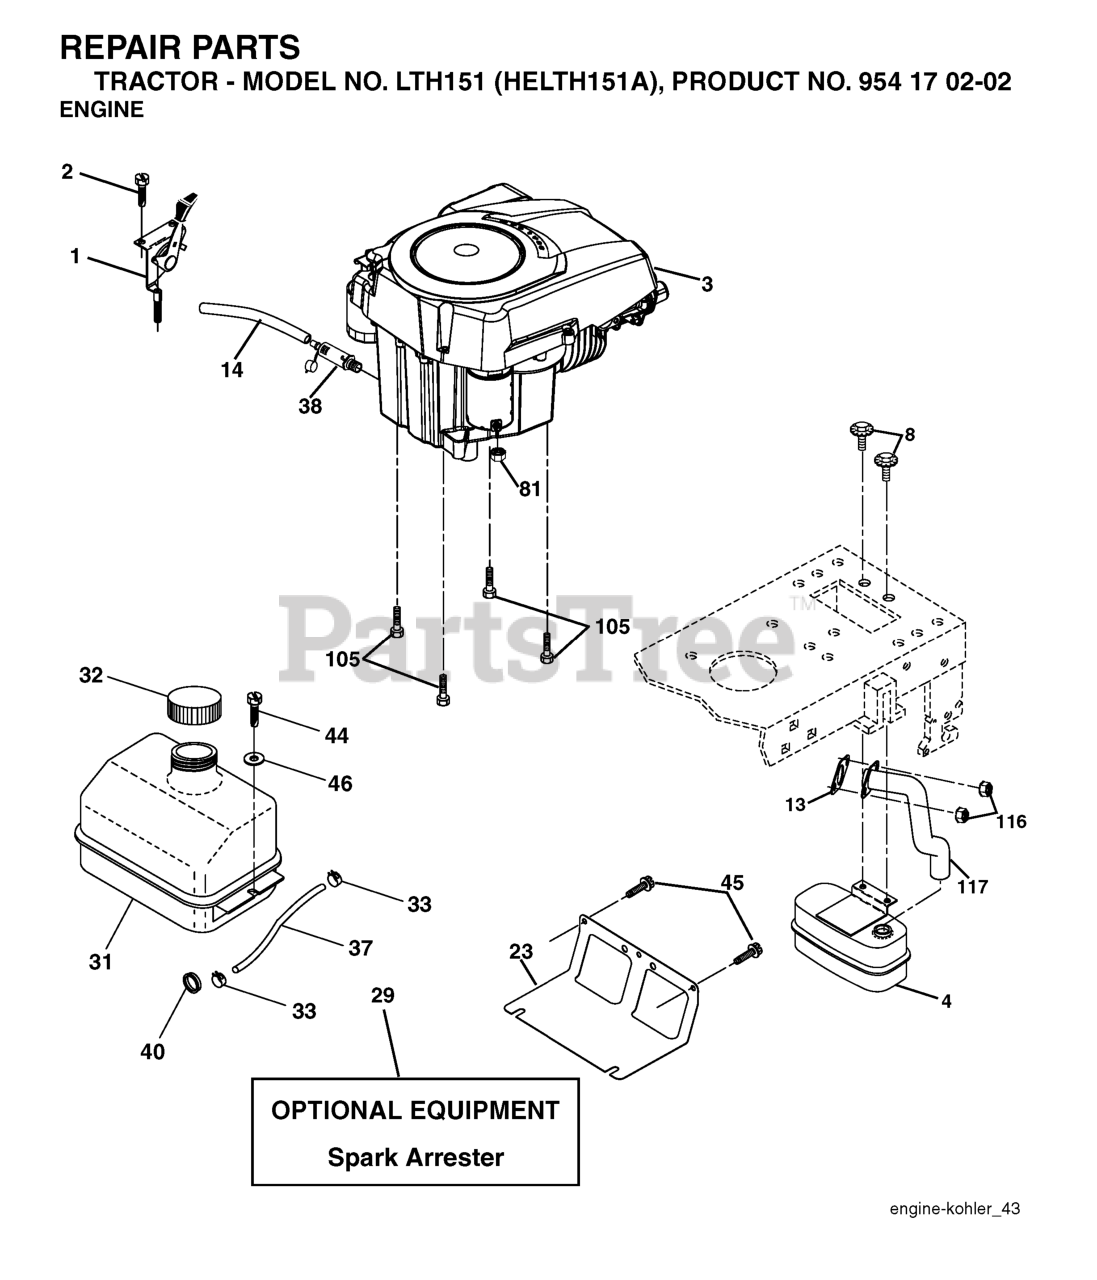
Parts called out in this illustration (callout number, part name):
1	CONTROL.THROTTLE.LT/YT
2	SCREW
4	MUFFLER.SINGLE.CYL.KOHL/B&S
8	BOLT.5/16-18UNCX3/4 W/SEMS.BLK
13	GASKET.EXHAUST.KOHLER
14	TUBE, DRAIN OIL ASM.
23	SHIELD.BROWNING.DBR.GUARD
29	KIT.SPARK ARRESTOR 794945 B&S
31	TANK.ASM.FUEL.FRONT.W/CAP
32	FUEL CAP
33	HOSE CLAMP
37	LINE.FUEL.20
38	PLUG DRAIN OIL EASY
40	BUSHING.SNAP.NYL.BLK.
44	SCREW HEXWSHR 1/4-20X3/4
45	SCREW, 3/8-16X3/4
46	WASHER
81	NUT
105	SCREW 3/8-16X1
116	NUT.HEX.FLANGE.TOPLOCK
117	RP.TUBE.EXHAUST.KOHL.COURAGE
